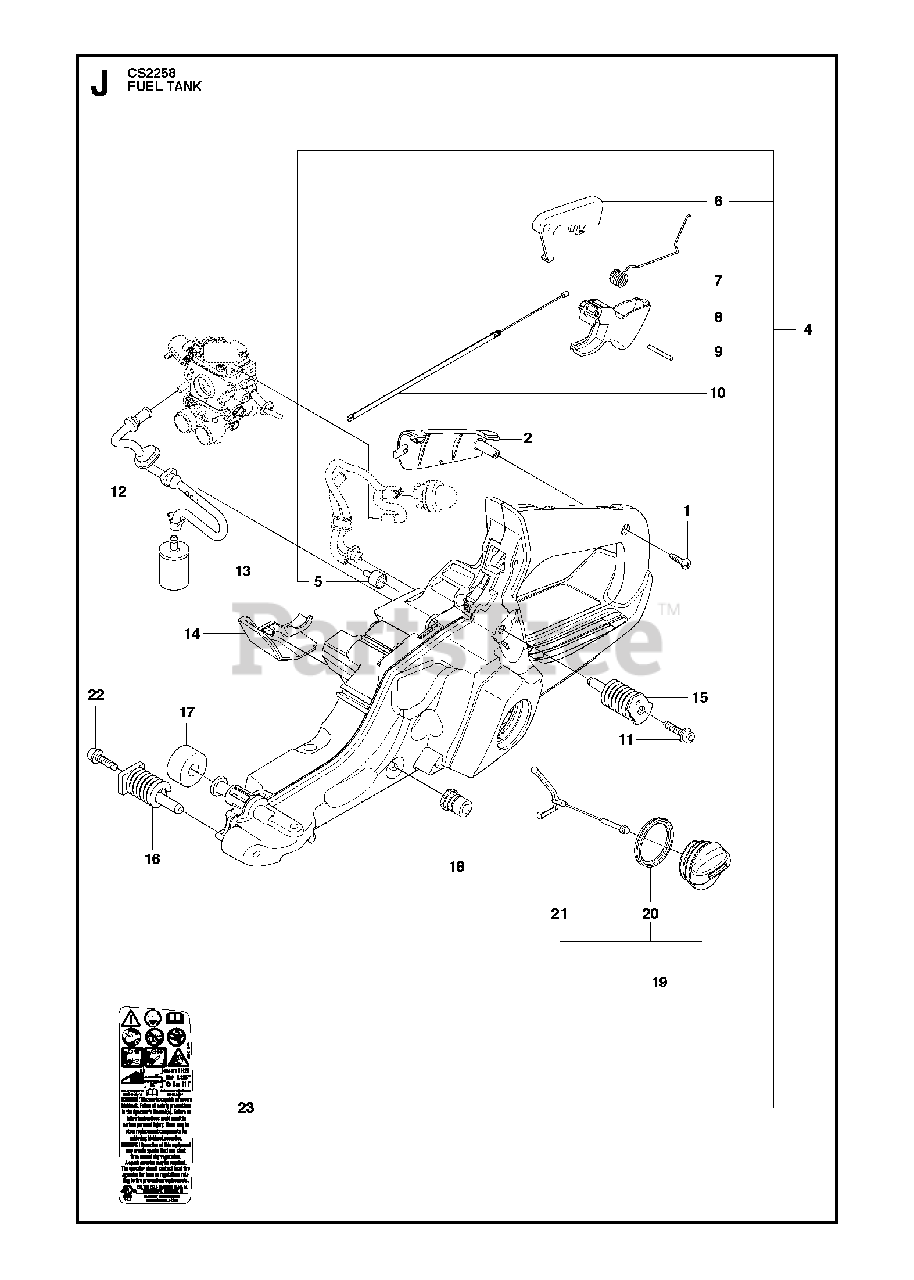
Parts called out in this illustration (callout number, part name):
2	HANDLE INSERT
5	FUEL TANK VENT
6	THROTTLE LOCKOUT
7	SPRING
8	THROTTLE
9	PIN
10	THROTTLE CABLE ASSY
12	RP FUEL HOSE
13	FUEL FILTER
14	COVER FUELTANK JONSERED BLACK
15	RP ANTIVIBRATION ELEMENT
16	ANITVIBRATION ELEMENT
17	DEFLECTION LIMITER
18	LATERAL SUPPORT
19	TANK CAP ASSY
20	SEALING
21	TANK LOCK
23	DECAL UL/CUL/SPARK ARRESTER 11
